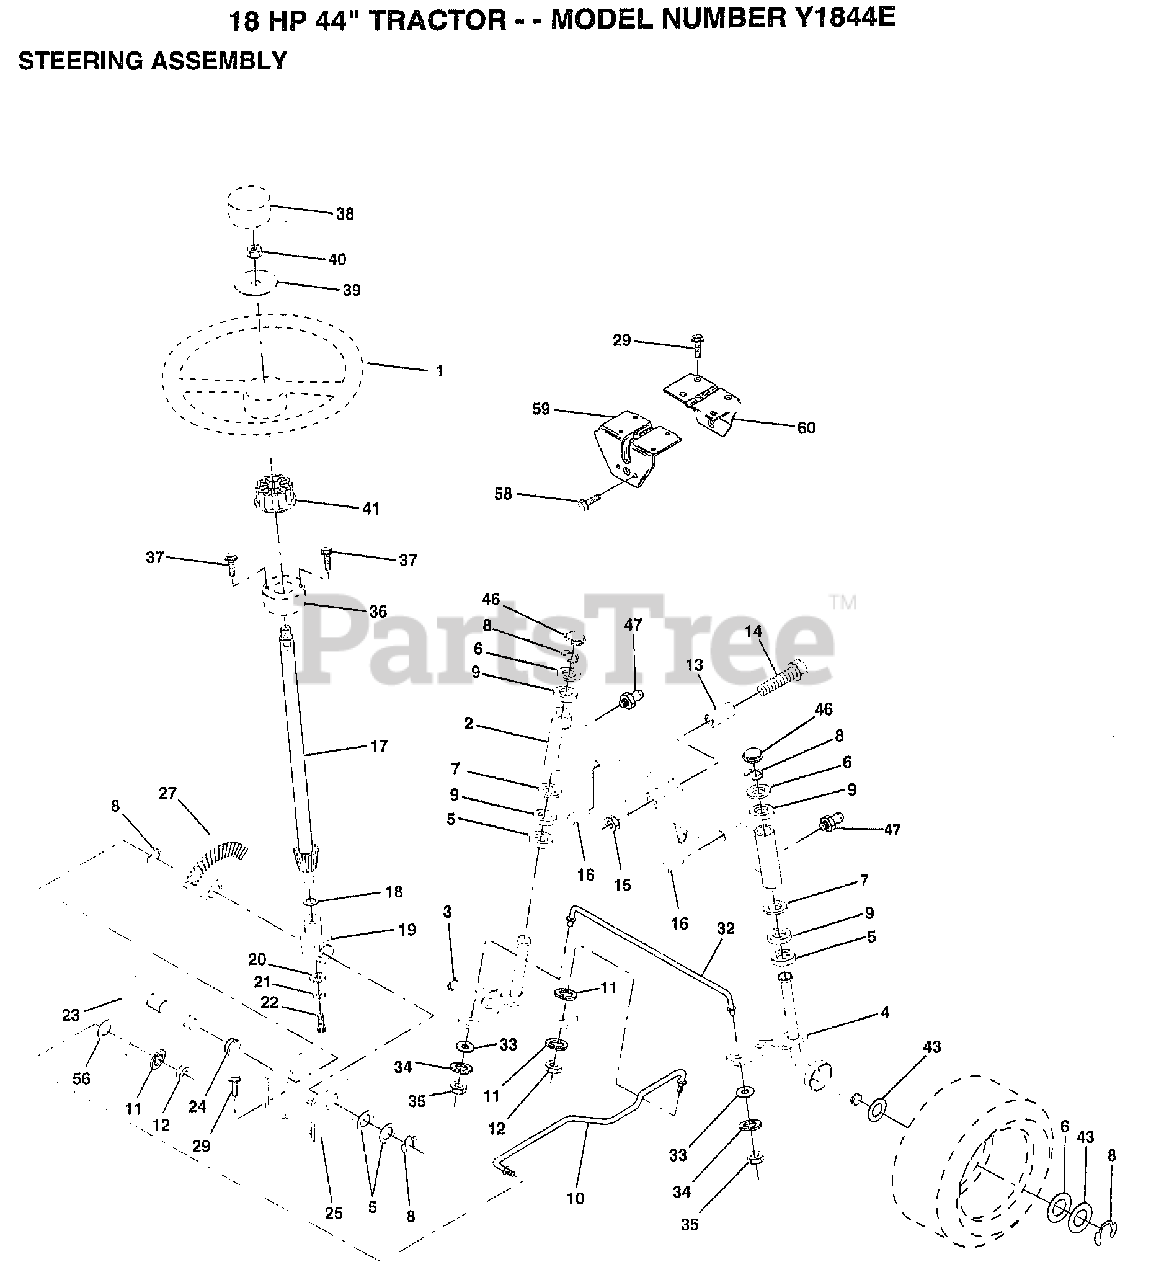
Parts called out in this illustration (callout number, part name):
1	WHEEL STR AYP BLK
2	AXLE ASM FRONT
5	WASHER .T
6	WASHER
7	WASHER
8	RING
9	COL. SRTG. BEAR.
11	LOCKWASHER
13	BEARING
14	BOLT LT
15	"NUT-LOC,FLANGE LT"
16	AXLE PIN
18	THRUST WASHER
19	SUPPORT.SHAFT
21	LOCKWASHER
22	"SCREW,SPECIAL"
24	NYLINER T
25	"BRKT,STEERING"
27	GEAR SECTOR
29	SCREW
32	TIE ROD
33	WASHER M
34	LOCKWASHER
35	NUT.LOCK.5/16-24
38	CAP STEER AYP
39	WASHER
41	ADAPTER LT
43	WASHER
46	CAP
47	ZERK M
56	WASHER
58	SCREW LT
59	SUPPORT-SADDL T
60	SUPPORT.SADDLE.FT
